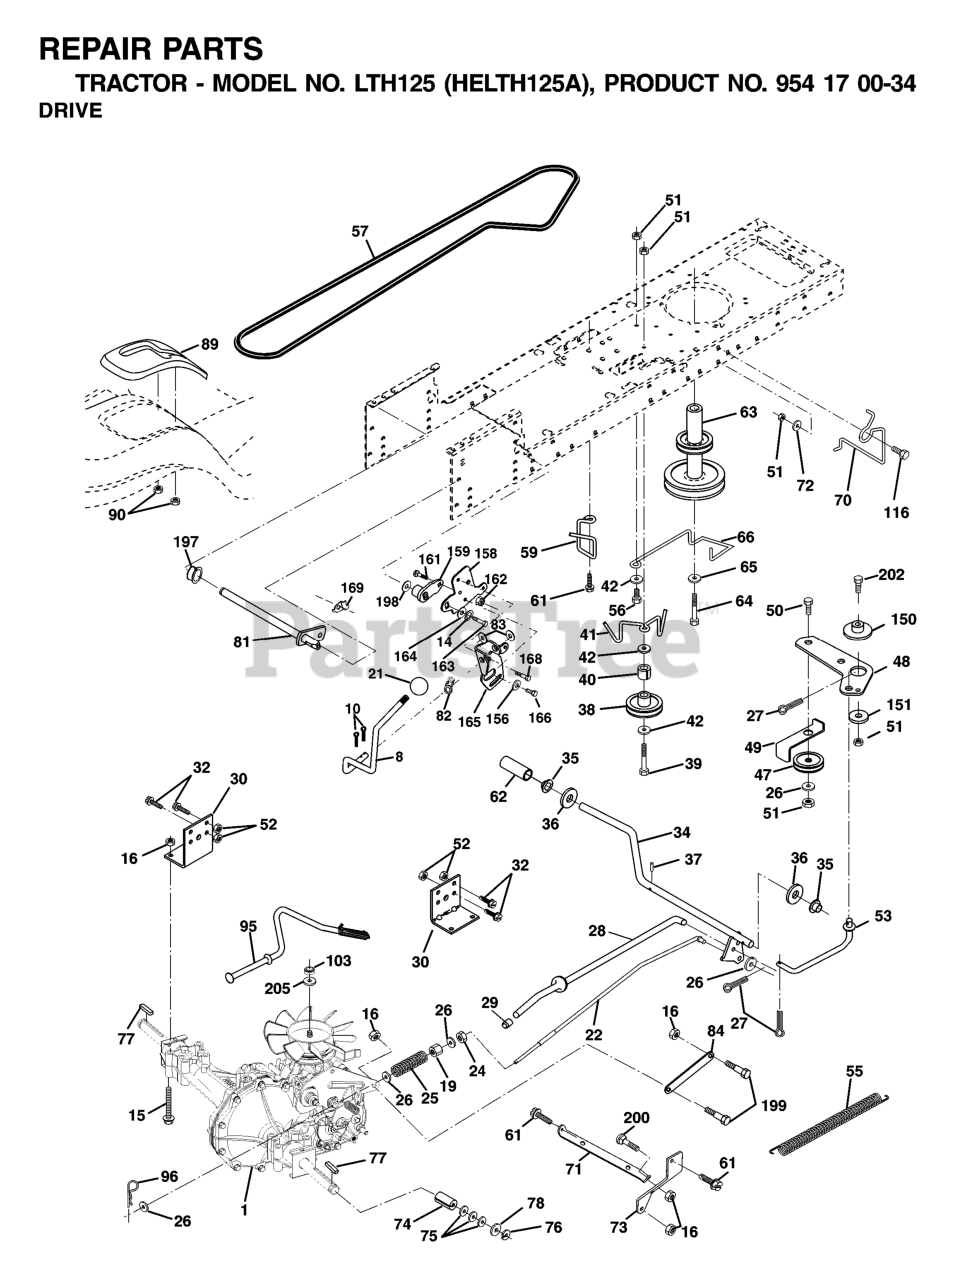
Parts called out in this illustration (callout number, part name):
8	ROD SHIFT FENDER ADJUST STLT
10	PIN COTTER
14	LOCKWASHER
15	BOLT HEX 5/16-18 GR 5
16	NUT.71038.31-18.HEX.NYLOCK
19	NUT
21	KNOB.DUCKHEAD.1/2
22	ROD BRAKE HYDRO
24	NUT
25	SPRING ROD LT
26	WASHER
27	COTTER PIN
28	ROD BRAKE PARK LT
29	PLUNGER CAP
30	BRKT, MOUNT TRNSAXLE
32	BOLT
34	SHAFT, FOOT PEDAL
35	BEARING.NYLON
37	DRIVE PIN
38	FLAT IDLER PULLEY
41	KEEPER.BELT.IDLER.FLAT
42	WASHER
47	IDLER PULLEY
48	BELLCRANK, CLUTCH
49	RETAIN BELT
50	BOLT
52	LOCKNUT
53	LINK, CLUTCH LT
55	SPRING, RETURN LT
57	DRIVE BELT, LTH & YTH TRACTORS
59	KEEPER, BELT CENTER
61	SCREW 3/8-16X3/4
62	PEDAL COVER T
63	PULLEY.ENG.CL.MECH.SLVR.LT/YT
64	BOLT
65	LOCKWASHER
66	KEEPER BELT ENGINE
70	KEEPER BELT ENG
71	STRAP TORQUE LH HYDRO
72	WASHER
73	STRAP TORQUE RH HYDRO
74	SPACER AXLE
77	SQUARE KEY
81	SHAFT ASM CROSS TAPERED
82	SHIFT SPRING
83	WASHER
84	LINK TRANSAXLE
90	NUT.PUSH.3/16
95	CONTROL ASM. BYPASS HYDRO
96	RETAINER M
103	NUT.HEX.1/2-20
116	BOLT
150	BUSHING.BELLCRANK.GRD.DR
151	WASHER 12/32X2X10GA
156	WASHER.SRRTD.5/16
158	BRACKET
159	HUB
161	BOLT
162	NUT.CROWNLOCK.1/4
164	Washer 5/8 x .281 x 10 Ga.
165	RP BRACKET
168	BOLT.SHOULDER.5/16-18X
169	PLATE.FASTENING.CROSS.SHAFT
197	NYLINER SNAP 5/8" ID
198	WASHER.NYL.7/8IDX.105"HYD CR
199	BOLT SHOULDER 5/16-18 UNC
202	BOLT.3/8-16X1.50
205	WASHER
